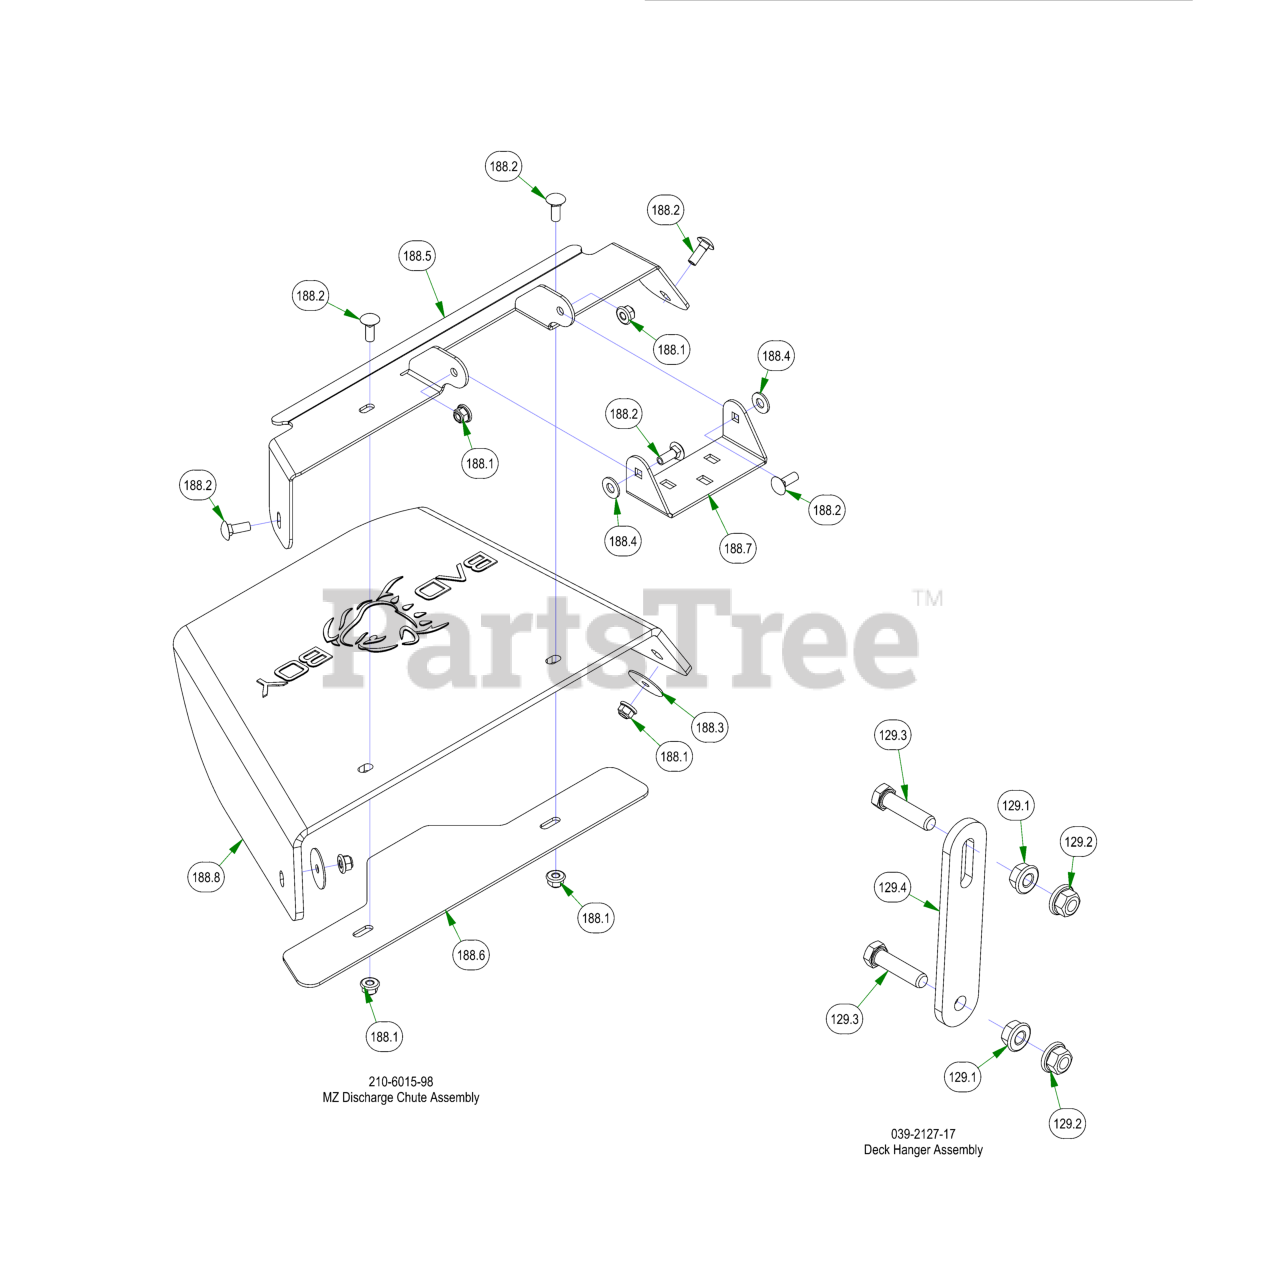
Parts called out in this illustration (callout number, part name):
129	Deck Hanger Assembly
129.1	3/8-16 HEX SERRATED FLANGE NUT HARD/ZINC
129.2	3/8-16 NYLON INSERT FLANGE LOCKNUT (GR.F) ZINC
129.3	3/8-16 X 1-1/2 HEX CAP SCREW (GR.5) ZINC
129.4	2017 MZ/ZT Deck Hanger
188	MZ Discharge Chute Assembly
188.1	5/16" Nylon Flange Nut
188.2	5/16" x 7/8" Carriage Bolt
188.3	5/16 Fender Washer
188.4	.360 ID Plastic Washer
188.5	Discharge Chute Bracket 48 MZ (Upper)
188.6	2017 MZ Discharge Chute Bracket-Lower
188.7	Chute Hanger 48 MZ
188.8	Rubber Discharge Chute MZ (Component)
